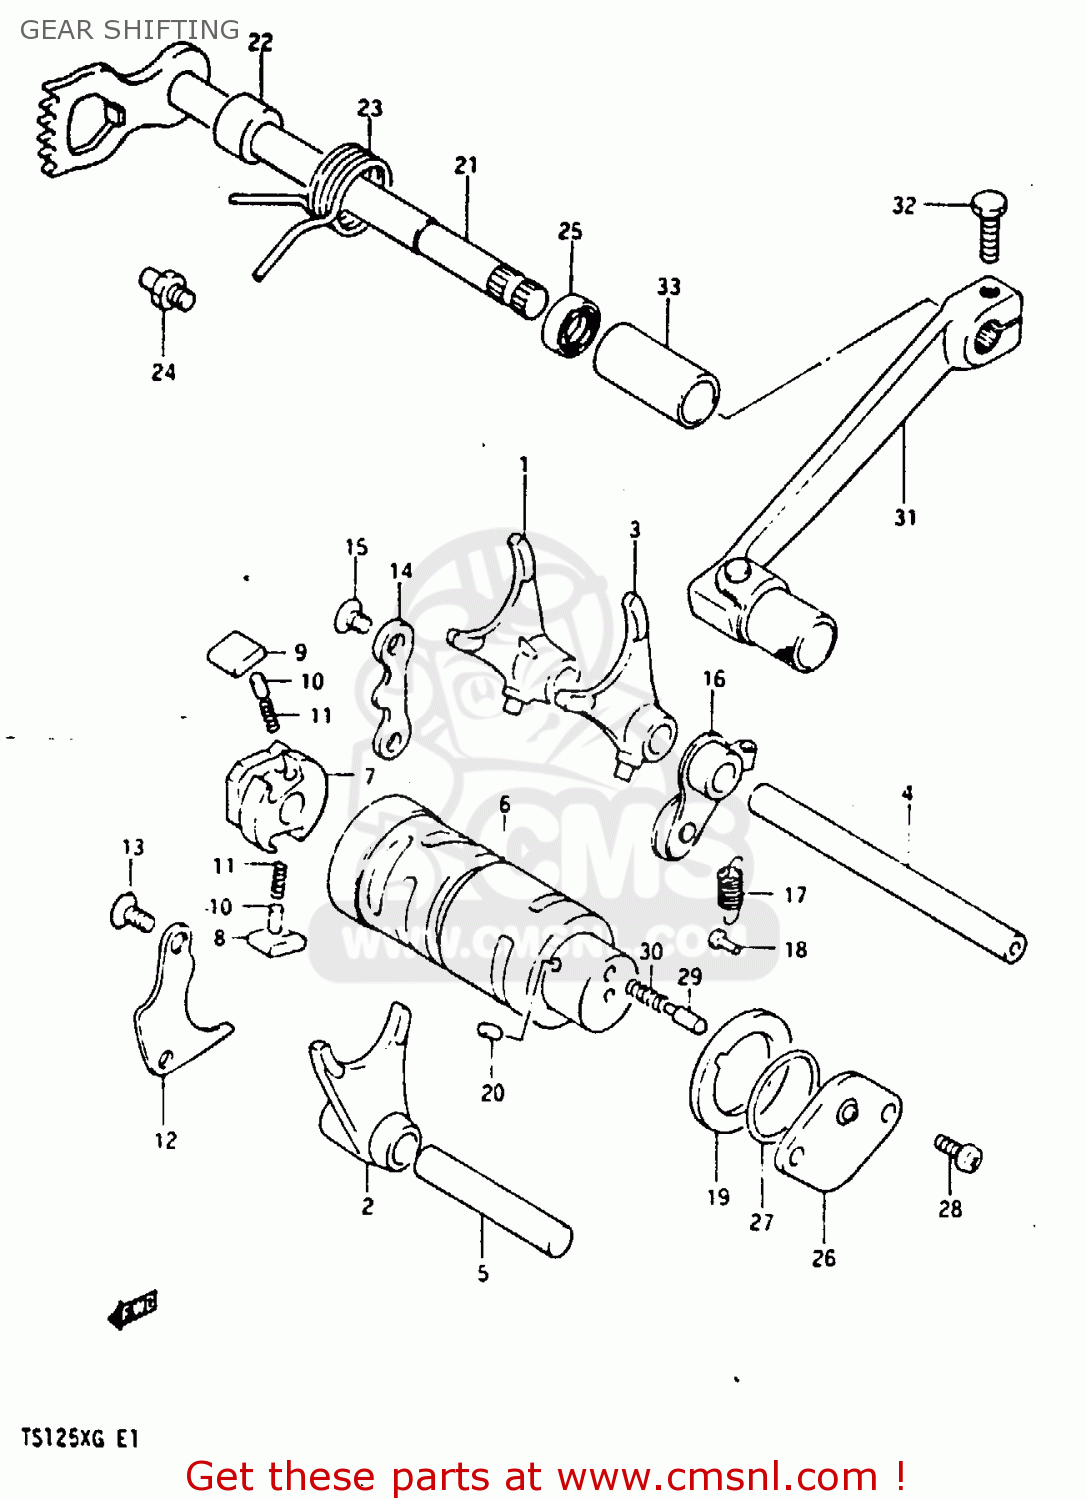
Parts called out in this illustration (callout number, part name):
1	FORK,GEAR SHIFT NO.1
2	FORK,GEAR SHIFT NO.2
3	FORK, NO.3
4	SHAFT,GEAR SHIFT FORK(L:109)
5	SHAFT,GEAR SHIFT FORK
6	CAM
7	GEAR,GEARSHIFT CAM DRIVE
8	PAWL,GEAR SHIFT NO.1
9	PAWL,GEAR SHIFT NO.2
10	PIN(5X8)
11	SPRING
12	LIFTER,GEAR SHIFT PAWL
13	SCREW
14	STOPPER,GEAR SHIFT POLE
15	SCREW
16	STOPPER, CAM
17	SPRING
18	RIVET
19	PLATE,GEAR SHIFT CAM STOPPER
20	PIN 4X6
21	SHAFT, GEAR SHIFTING
22	SPACER(12X20X15.3)
23	SPRING
24	STOPPER,GEAR SHIFT CAM
25	OIL SEAL
26	BODY,GEAR SHIFT SWITCH
27	O-RING (D:2.4 ID:26.2)
28	SCREW
29	PIN(5X15.5)
30	SPRING
31	LEVER ASSY,GEAR SHIFT
32	BOLT
33	CUSHION
